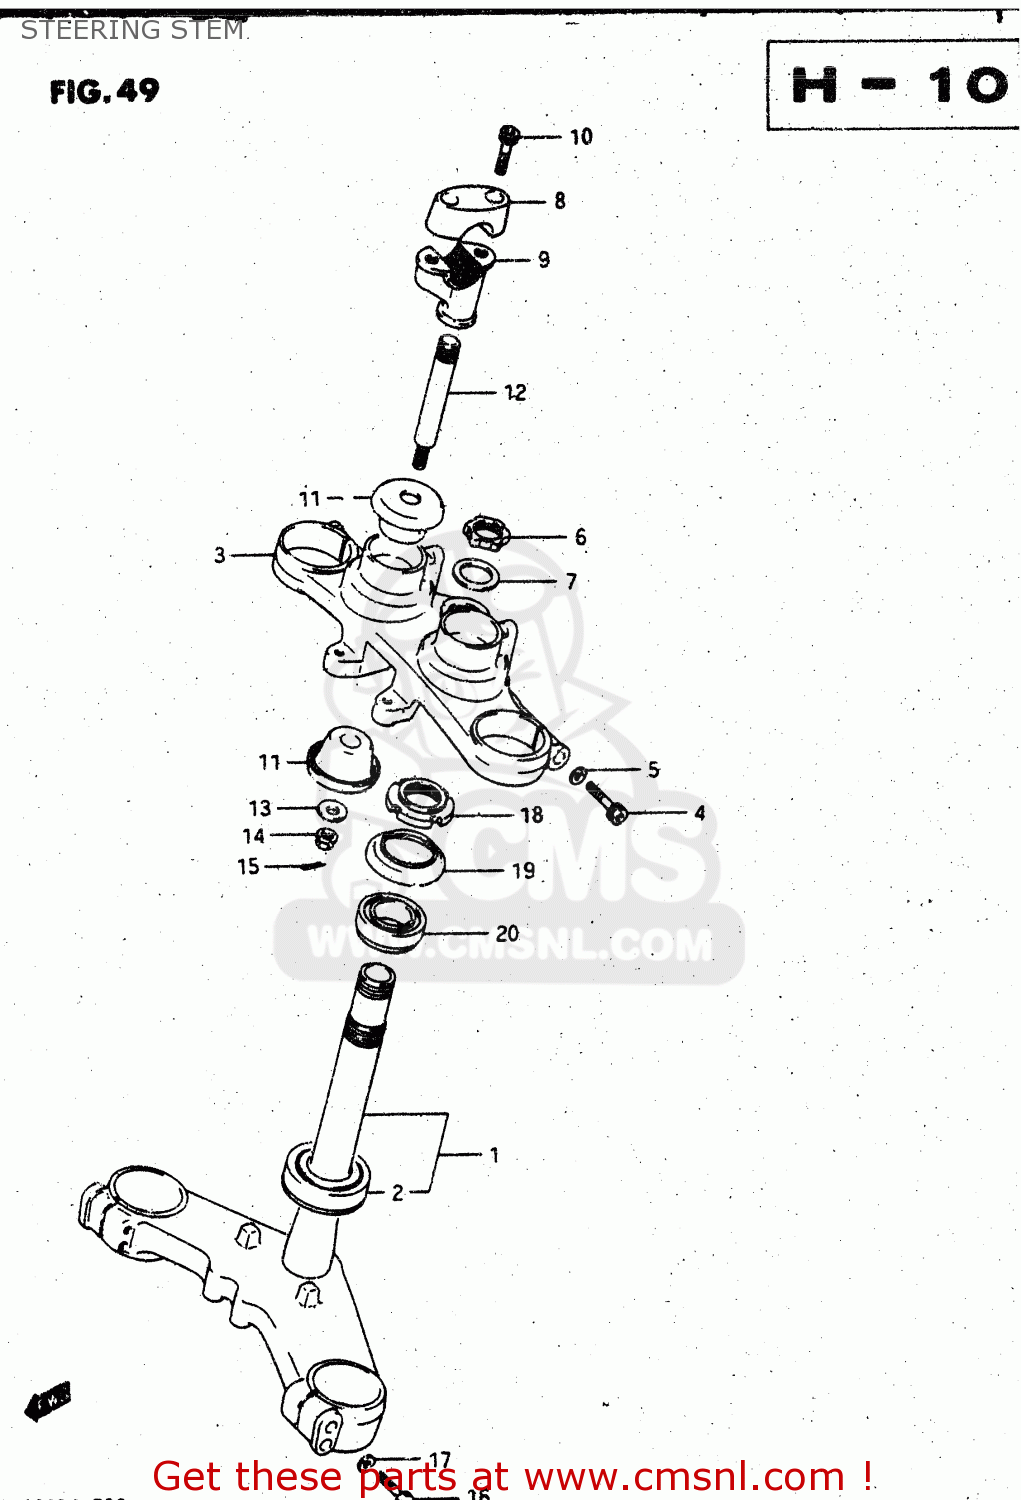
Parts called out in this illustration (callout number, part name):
1	STEM,STEERING
2	BEARING
3	HEAD,STEERING STEM
4	BOLT
5	LOCK WASHER
6	NUT,STEERING STEM
7	WASHER,STEERING STEM
8	HOLDER,HANDLE,UPPER
9	HOLDER,HANDLEBAR
10	BOLT, FRONT LH
11	CUSHION
12	BOLT
13	WASHER,STEERING STEM
14	NUT
15	COTTER PIN
16	BOLT 8X40
17	LOCK WASHER
18	NUT,STEERING STEM(25X44X10)
19	DUST SEAL,STEERING,UPPER
20	TAPER,ROLLER BEARING
